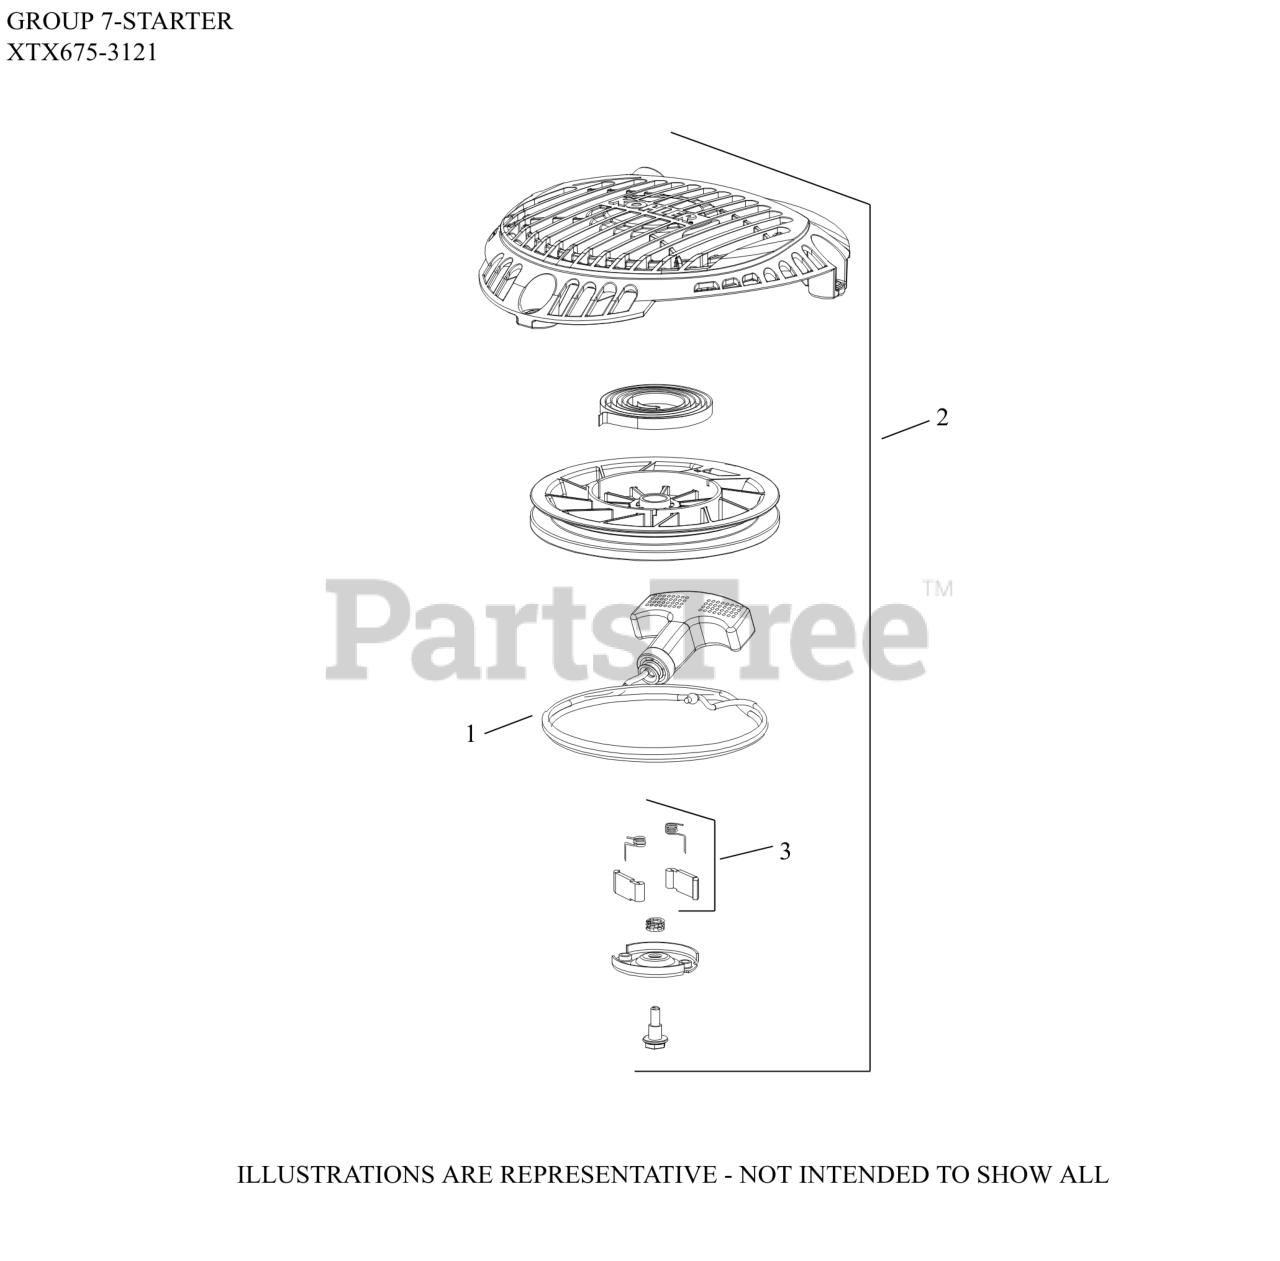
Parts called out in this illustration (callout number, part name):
1	KIT, STARTER ROPE W/HANDLE
2	STARTER ASSEMBLY, RETRACT
3	KIT, PAWL REPAIR
